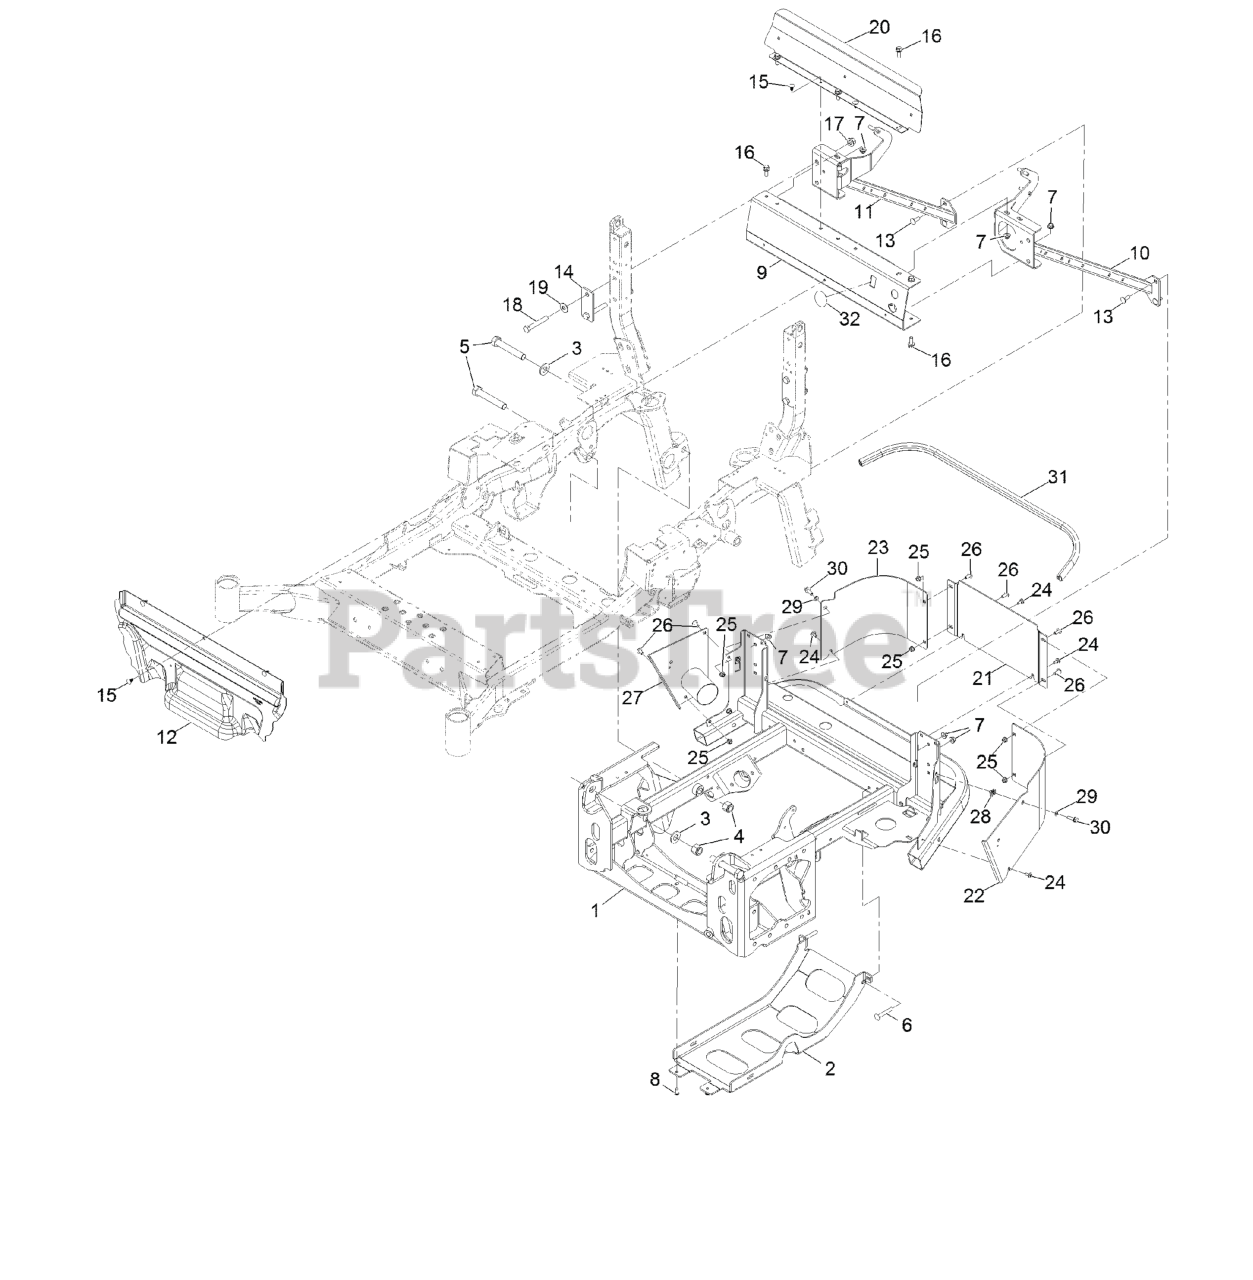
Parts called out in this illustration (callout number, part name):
1	FRAME-POWER
2	PLATE-SKID
4	NUT-LOCK, NI
5	SCREW-HH
6	SCREW-CARR
7	NUT-HF, NI
8	SCREW-BHTF
9	CHANNEL-CROSS
10	BRACE-ROPS, LH
11	BRACE-ROPS, RH
12	PANEL-DEFLECTOR, HEAT
13	SCREW-CARR
14	PLATE-SPACER
15	PLUG-PLASTIC
16	SCREW-HHF
17	Nut-Lock 1/2-13
18	SCREW-HH
19	WASHER-SPRING
20	SHIELD-AIR
21	PLATE-BUMPER, CENTER
22	PLATE-BUMPER, LH
23	PLATE-BUMPER, RH
24	SCREW-SHOULDER
25	NUT-HF, NI
26	SCREW-TORX
27	PLATE-EXHAUST
29	WASHER-BELLEVILLE
30	SCREW-HHF
31	SEAL-BULB
32	DECAL-COVER
